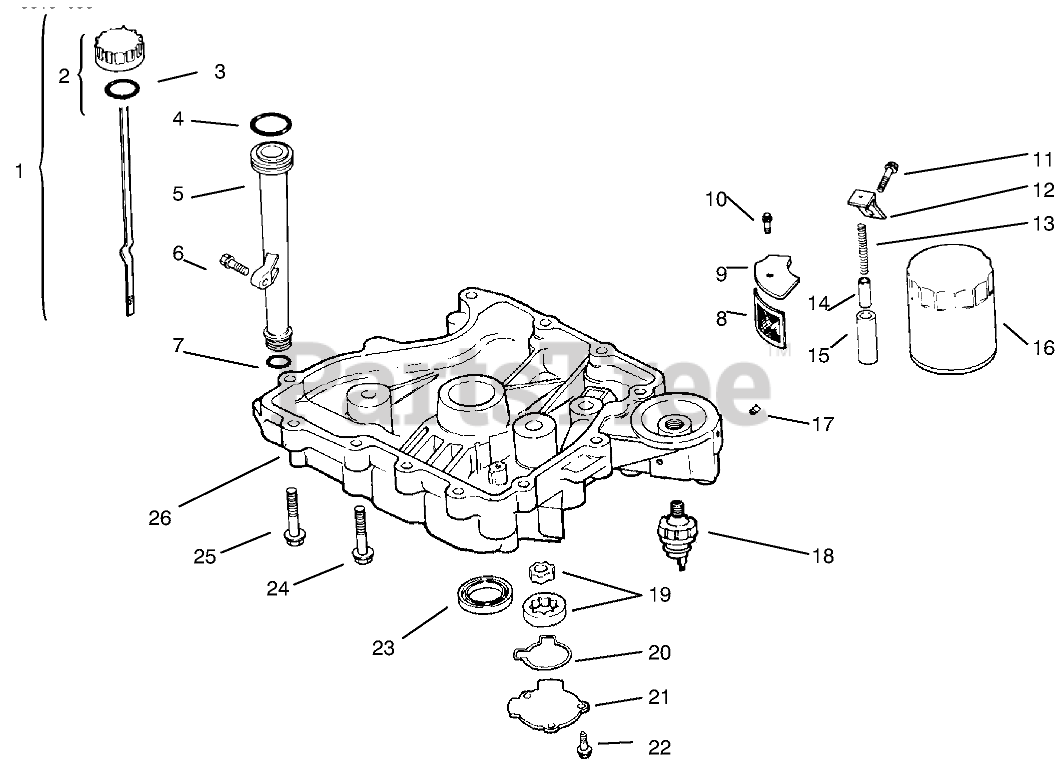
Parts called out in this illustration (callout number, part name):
1	Dipstick INC 2-3
2	Kit-Oil Cap INC 3
3	O Ring-Fill Cap
4	"O" Ring-Upper Tube
5	Tube-Oil Fill
7	O Ring-Lower Fill Tube
8	Screen-Oil Pickup
9	Cover-Oil Pickup Screen
10	Screw-HF
11	Screw
12	Bracket-Oil Pump Relief
13	Spring-Oil Relief Valve
14	Piston-Oil Relief Valve
15	Body-Oil Relief Valve
16	Filter-Oil
17	Plug
18	Switch-Oil Pressure
19	Pump-Oil
20	O Ring-Oil Pump Cover
21	Cover-Oil Pump
22	Screw-HF
23	Seal-Crankshaft
24	Screw M8x1.25x45
25	Screw M8x1.25x45
26	Pan-Oil
